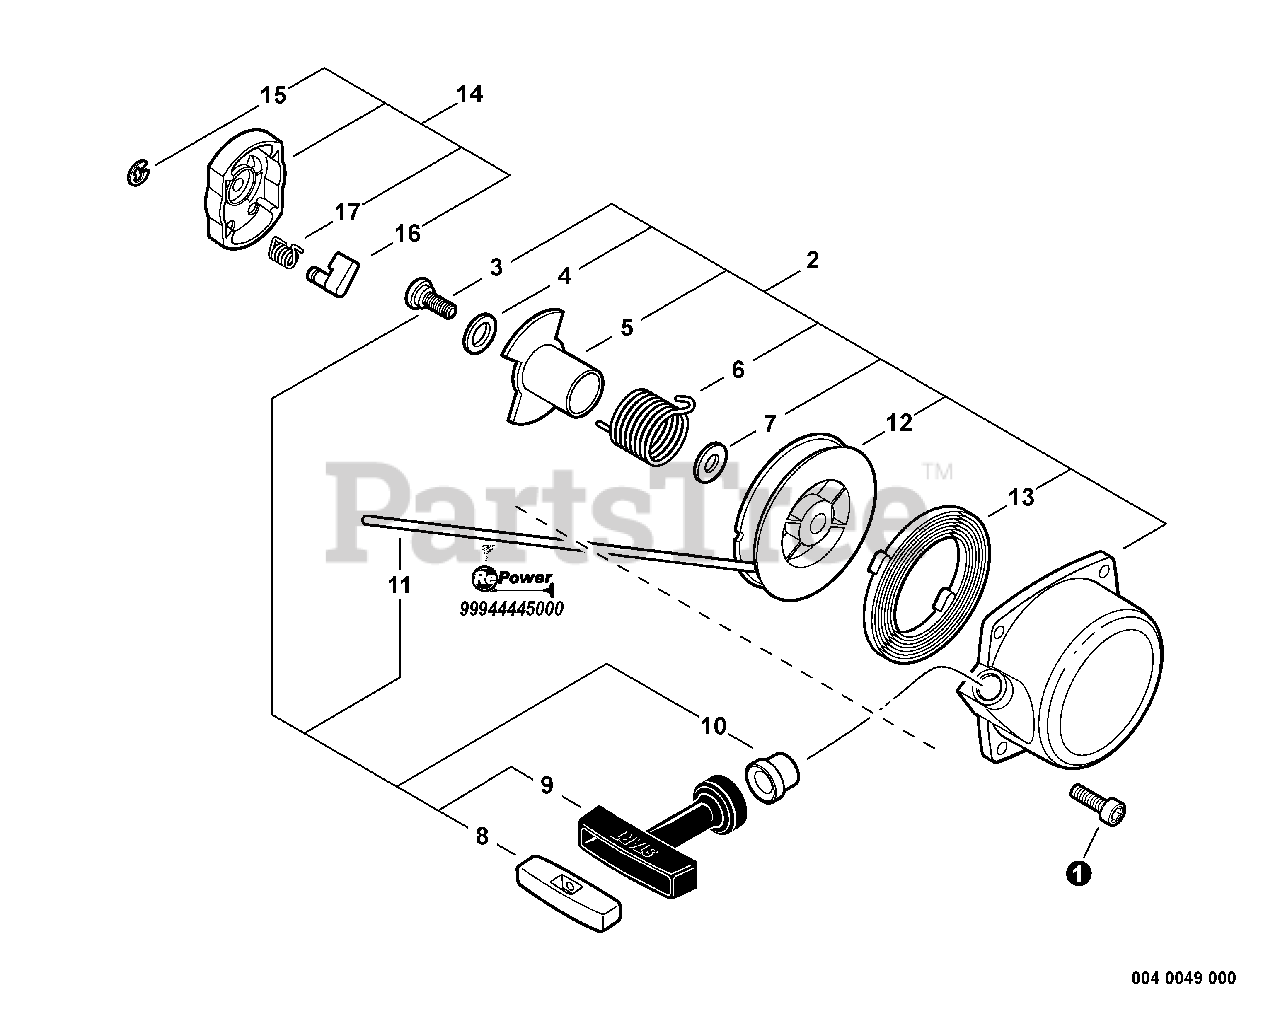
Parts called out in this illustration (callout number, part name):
1	SCREW - 5X16
2	STARTER ASSY
3	SCREW
4	WASHER, THRUST
5	CATCHER, PAWL
8	RETAINER, ROPE
9	GRIP, STARTER
10	GUIDE, ROPE
11	ROPE, STARTER - 3.5X1000
12	REEL, ROPE
13	SPRING, REWIND
14	STARTER PAWL ASSY
15	RING, RETAINING - 4
16	PAWL, STARTER
17	SPRING, RETURN
180	RePower BULK ROPE - 200 FEET
